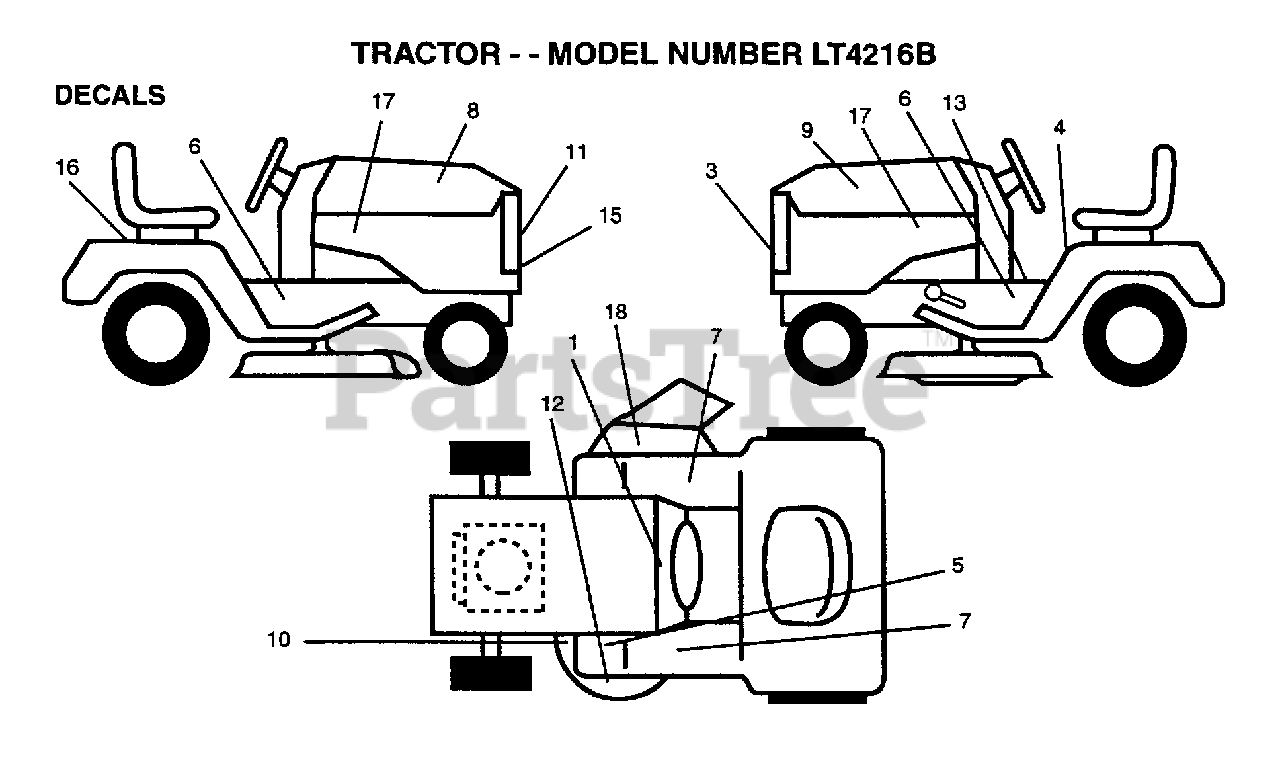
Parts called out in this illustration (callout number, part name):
1	DECAL INST OP DAS
3	DECAL LOGO GRILLE
4	DECAL CAUT FEND
5	DECAL CLUT/BRAKE
6	DECAL CHASSIS KGR
7	FOOTREST PAD
8	DECAL.HD.RH.KGRO
9	DECAL.HOOD.LH.KGR
10	DECAL
11	DECAL.GRILLE.KGRO
12	DECAL DECK MULCH
13	DECAL BRAK PARK
15	DECAL.GRILLE.KGRO
16	DECAL FEND QUICK
18	DECAL DANGER CT/F
